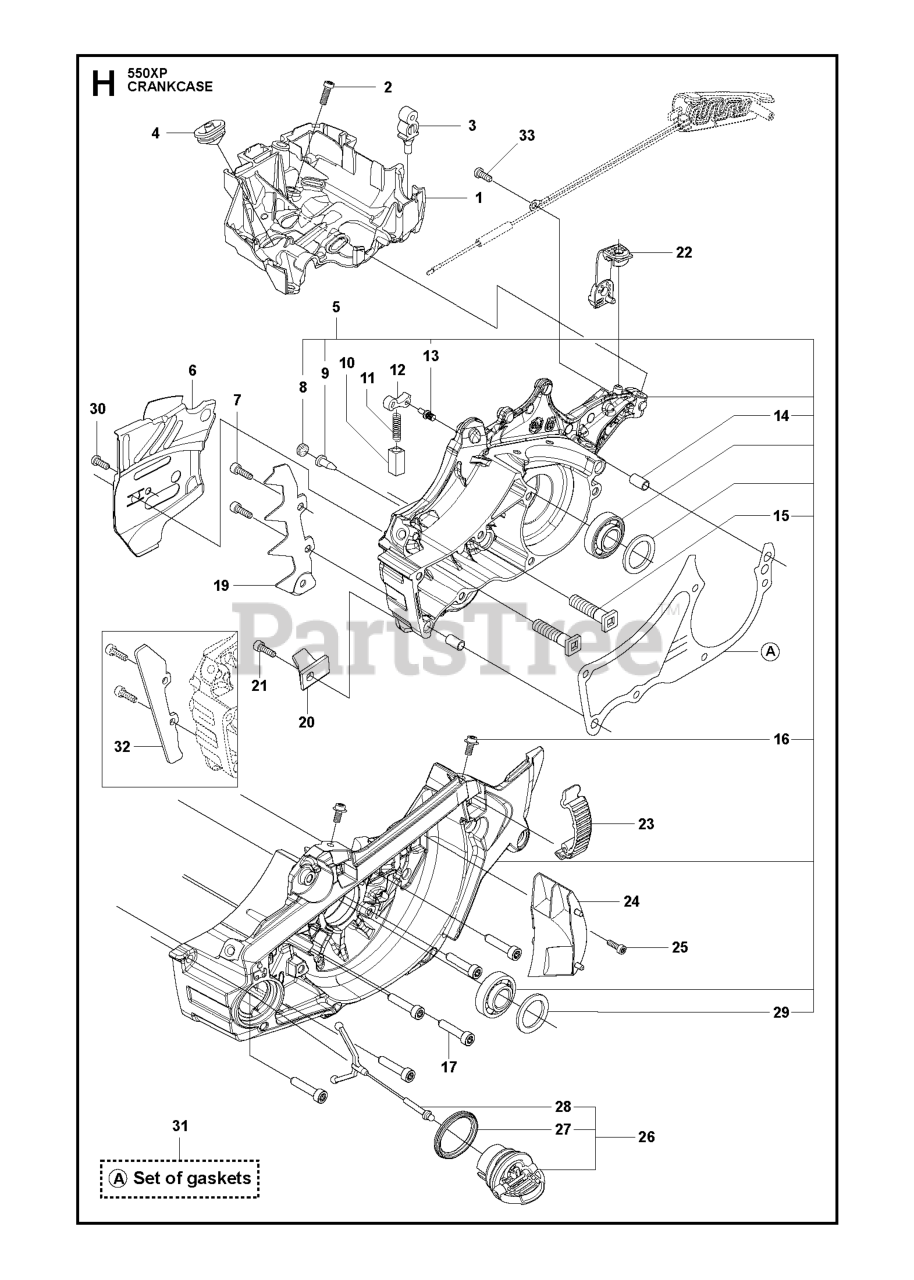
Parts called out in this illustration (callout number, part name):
1	CARBURETTOR AREA BASE
2	SCREW ITXSCFM
3	SUPPORT
5	CRANKCASE ASSY
6	CHAIN GUIDE PLATE
7	SCREW ITXPANM M5X16 T27 10.9
8	PLUG
9	VALVE-CHECK (DUCKBILL)
11	LOCK SPRING
14	SLEEVE
16	SCREW ITXSCM WASHER M5X12 T27
17	SCREW ITXSCM M5X25 12.9 TBO T
20	CHAIN CATCHER
22	DEFLECTION LIMITER
23	CLIP GRAY
24	AIR NOZZLE
25	SCREW ITXSCM M4X15 T27 12.9 T
26	TANK CAP ASSY
27	GASKET TANK CAP
29	RADIAL SEAL
30	SCREW CITXPANT
31	GASKET KIT 50CC
32	BUMPER, BAG
